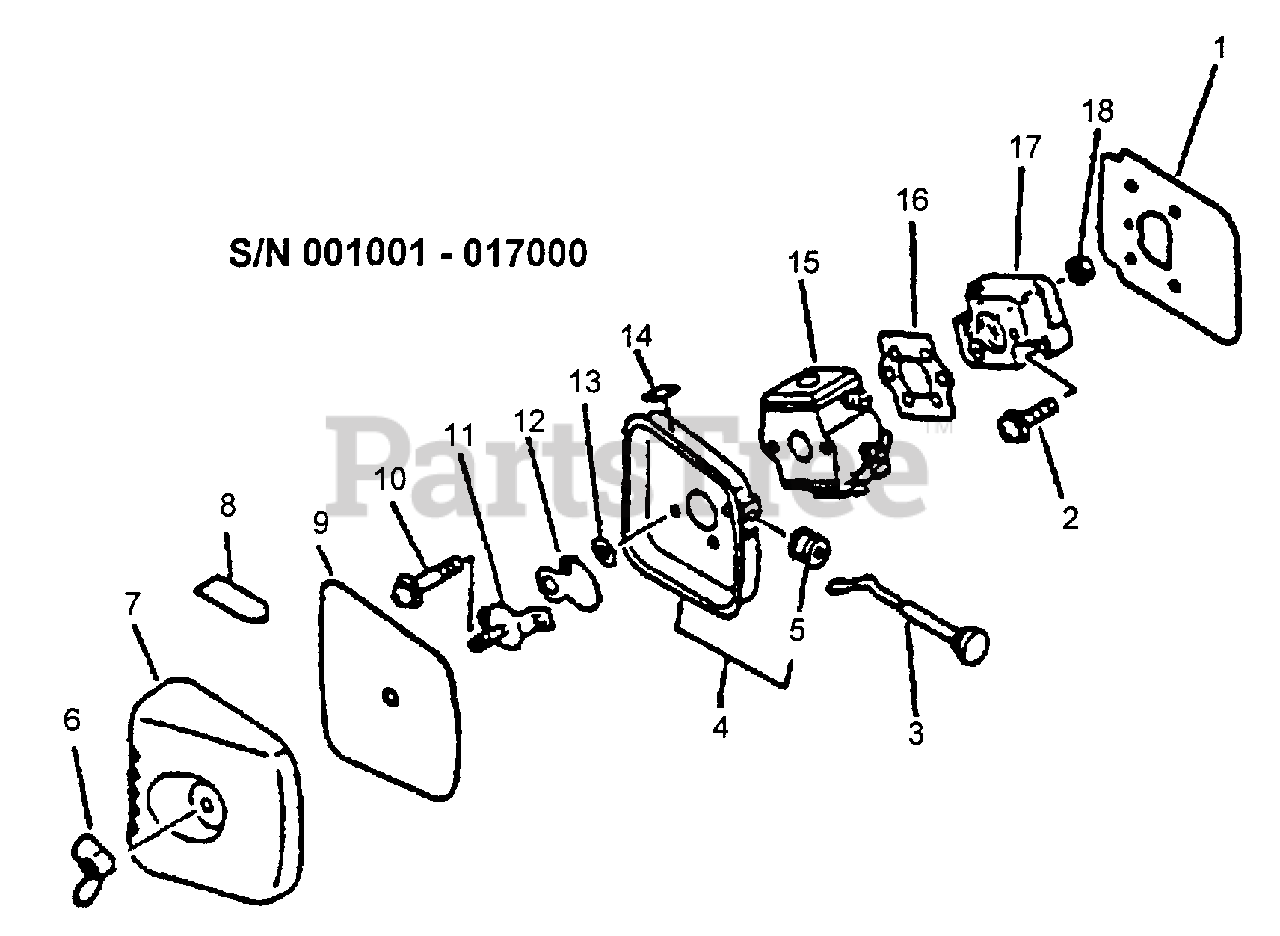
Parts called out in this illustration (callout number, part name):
1	SHIELD, INTAKE
2	SCREW - 5X20
3	ROD, CHOKE
4	CASE, AIR FILTER
6	WINGNUT - 6
7	COVER, AIR FILTER
8	LABEL - CHOKE
9	FILTER, AIR
10	SCREW - 5X57
11	PLATE, PREVENT
12	SHUTTER, CHOKE
13	WASHER - 5
14	LABEL - IDLE
15	CARBURETOR C1U-K10A
16	GASKET, INTAKE
17	INSULATOR, INTAKE
